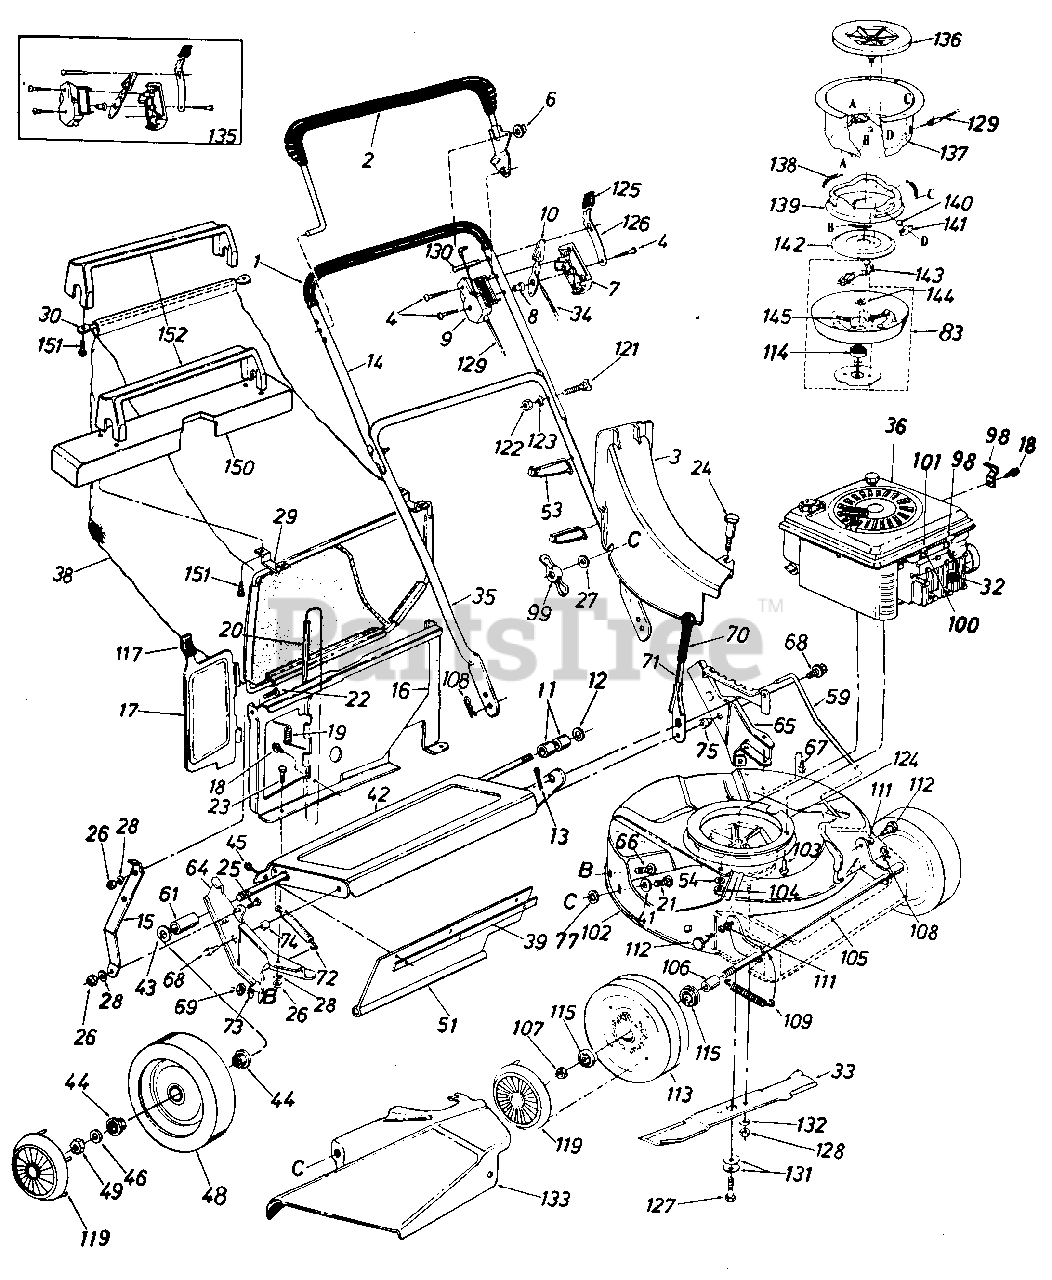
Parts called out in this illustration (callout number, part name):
2	Control Handle Ass'y. L.H.
3	Top Discharge Chute Ass'y.
4	Truss Mach. Scr. #12 x 1.50" Lg.
6	Push Cap
7	Control Panel Half
8	Control Disc Pin
9	Clutch Panel Half
10	Throttle Control Lever
11	Spacer .526" I.D. x .690" O.D. x .640" Lg.
12	Fl-Wash. .531" I.D. x .930" O.D.
13	Cotter Pin 3/32" Dia. x.75" Lg.
14	Upper Handle Chrome
15	Panel Support Brkt.
16	Top Catcher Panel
17	Top Door
18	Hex "B" Tap Scr. #10 x .38" Lg.
19	Torsion Spring .20" I.D. x 1.14" Lg.
20	Pivot Pin .187" Dia. x 7.25" Lg.
21	Carriage Bolt 2/4-20 x .62"
22	Truss Mach. Scr. 1/4-20 x 1/2" Lg.
23	Hex Bolt 1/4-20 x .50" Lg.
24	Shld. Bolt .312" Dia. x .18" Lg. Special
25	Truss Mach. Scr. 1/4-20 x .62" Lg.
26	Hex Nut 1/4-20 Thd.
27	Fl-Wash. .280" I.D. x .620" O.D.
28	L-Wash 1/4" I.D.
29	Front Grass Catcher Frame
30	Upper Bag Support
32	Spark Plug Insulator
33	21" Blade
34	Throttle Control Wire 45"
35	Lower Handle Chrome
36	Engine
38	21" Top Discharge Grass Bag
39	Retaining Strip
41	Fl-Wash. .344" I.D. x .62" O.D.
42	Rear Axle Ass'y.
43	Fl-Wash. .531" I.D. x .930" O.D.
44	Flange Ball Bearing 1/2" I.D.
45	Hex AB-Tap Scr. 1/4 X .62"
46	Fl-Wash. .531" I.D. x .930" O.D.
48	Rear Wheel Ass'y. Comp. 8x 1.75
49	Hex L-Nut 1/2-20 Thd.
51	Rear Flap 3.75" x 17.30" Lg.
53	Cable Tie
54	L-Wash. 1/4" I.D.
59	Height Adj. Rod
61	Spacer .513" I.D. x .703 O.D. x .69" Lg.
64	R.H. Handle Wheel Brkt. Ass'y.
65	L.H. Handle Wheel Brkt. Ass'y.
66	Carriage Bolt 5/16-18 x .62"
67	Hex Wash. Hd. B-Tap Scr. 5/16-1 8
68	Hex Wash. Hd. TT-Tap Scr. 3/8-16
69	Hex Nut 5/16-18 Thd.
71	Height Adj. Lever
72	Extension Spring .50" O.D. x 3.80" Lg.
73	Bell-Wash. .345" I.D. x .88" O.D.
74	Spacer .385" I.D. x .502" O.D. x .270" Lg.
75	Shld. Spacer .500" Dia. x . 1 00
77	Bolt Retainer 1/4 x .50" O.D.
83	Clutch Blade Housing Ass'y.
98	Casing Clamp
99	Wing Nut
100	Hex B-Tap Scr. #10 x .62" Lg.
101	Casing Clamp
104	Speed Nut 1/4-20 U-Type
105	Front Axle Ass'y.
106	Sleeve .526" I.D. x .690" O.D. x .880" Lg.
107	Hex L-Nut 1/2-20 Thd.
108	Intern. Cotter Pin 5/16" Dia.
109	Extension Spring .50" O.D. x 3.20" Lg.
111	Intern. L-Wash. 3/8 x .56" O.D.
112	Shld. Bolt .623" Dia. x .425
113	Front-Wheel Ass'y. Comp. 7x 1.75
114	Ball Brg. .669" I.D. x 1.574"
115	Flange Ball Bearing 1/2" I.D.
117	Door Grip x 2.5
119	Hub Cap
121	Curved Carr. Bolt 5/16-18 x 1.38" Lg.
122	Hex Nut 5/16-18 Thd.
123	L-Wash. 5/16" I.D.
124	Blade Brake Clutch Comp.
125	Spring Lever Knob
126	Lockout Spring
127	Hex Cent. L-Bolt 3/8-24 x 2.00" (Grade 8)
128	Hex Nut 3/8-24 Thd. (Grade 8)
129	BBC Clutch Cable 46"
130	Lock Pin .314" Dia. x 1.75"
131	Bell-Wash. .400" I.D. x .88" O.D.
132	L-Wash. 3/8" I.D.
133	Side Chute Deflector
135	Kit Control Housing Comp.
136	Fan Adapter
137	Clutch Housing
138	Extension Spring .35" O.D. x 1.75" Lg.
139	Brake Cup Cone
140	Steel Ball .500" Dia.
141	Ball Block
142	Clutching Cone
143	Hex Tap L-Scr. 1/4-20 x .75"
144	Fl-Wash. .690" I.D. x 1.060" O.D.
145	Compression Spring .35" O.D. x 2.00" Lg.
150	Catcher Frame Cover
151	Truss Mach. Tap Scr. 1" Lg.
152	Bag Handle
